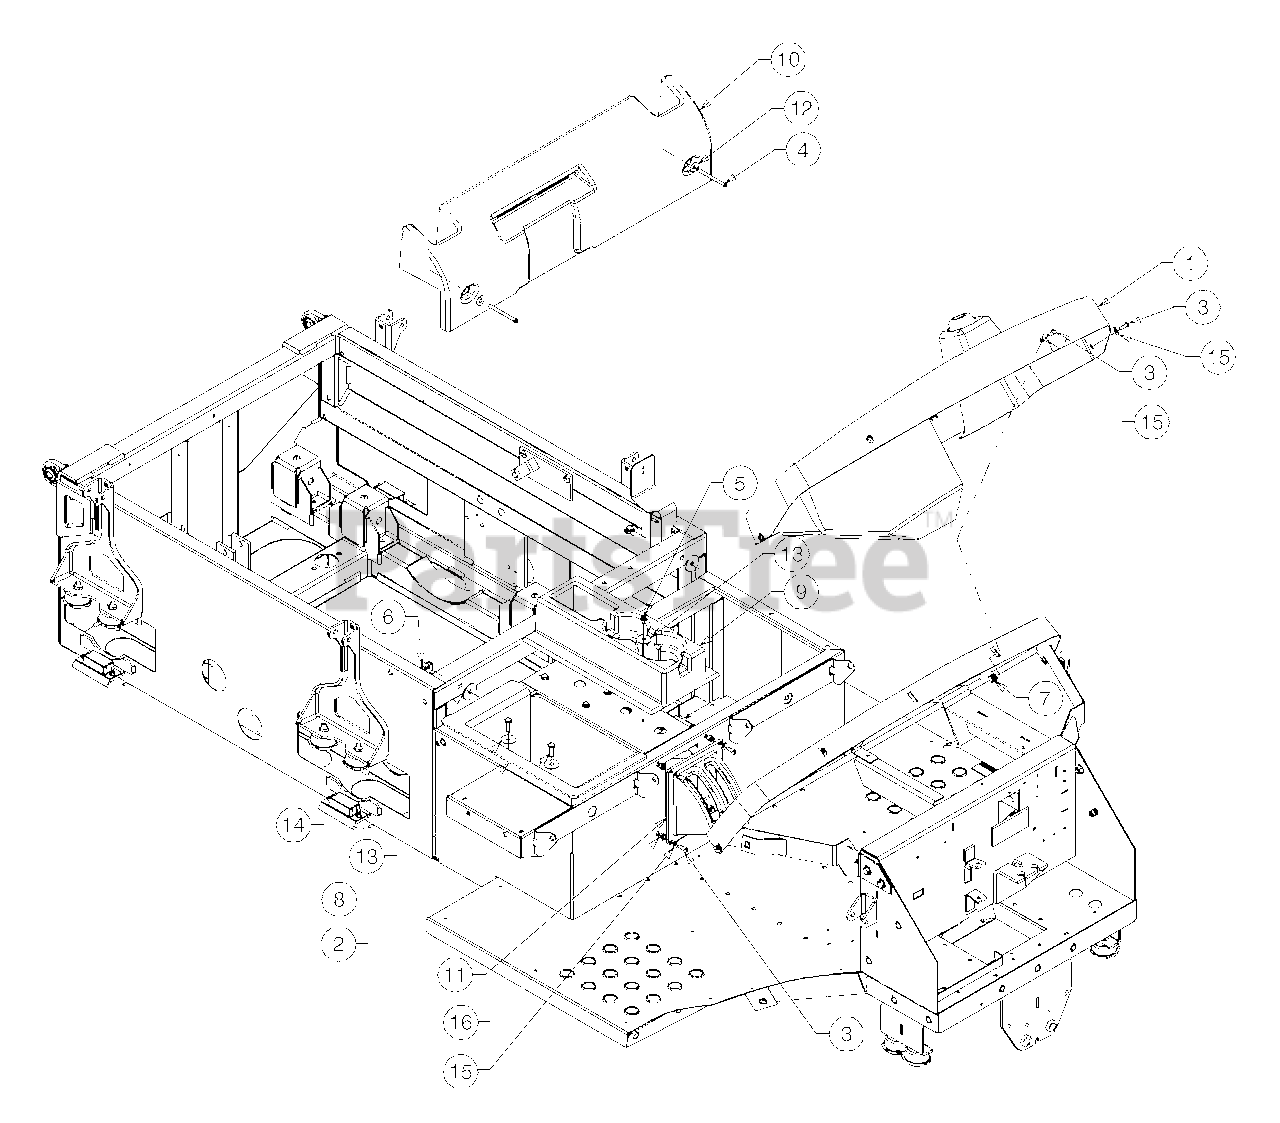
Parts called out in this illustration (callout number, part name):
1	Dash Assembly
2	Machine, Screw, 1/4-20 x .75
3	Screw, 1/4-20 x 3.0
4	Screw, Self-tapping, 1/4-20 x 0.500
5	Hex Screw, 5/16-18 x 1.0, Gr5
6	Nut, Retainer, 1/4-20
7	Wing Nut, 1/4-20 (w/ Bell Washer)
9	Console, Cup Holder
10	Panel, Airbox Cover
11	Panel, Shift Cover
12	Flat Washer, .350 x 1.25 x .06
13	Washer, Rubber, .375 x 1.5 x 1.25
14	Washer, Flat, .3125 x .875 x .04
15	Washer, Flat, .271 x .630 x .065
16	Insert, 1/4-20
